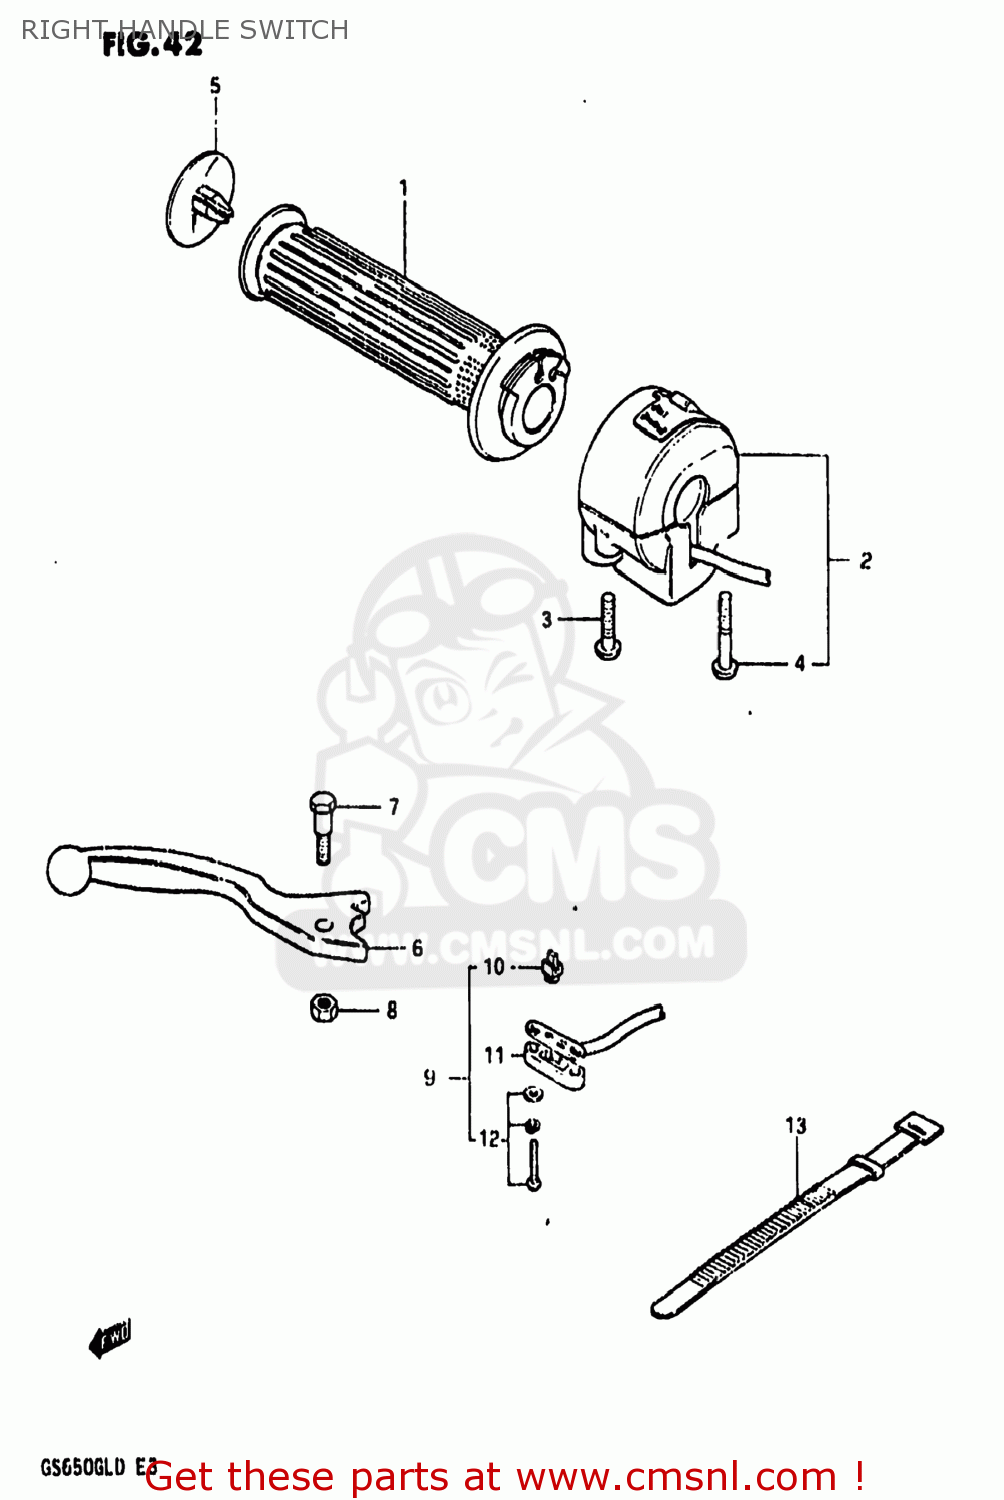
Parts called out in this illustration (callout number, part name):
1	GRIP,THROTTLE
2	SWITCH ASSEMBLY,HANDLE,RIGHT
3	SCREW
4	SCREW
5	CAP,GRIP END
6	LEVER,BRAKE
7	BOLT
8	NUT 6MM
9	SWITCH ASSEMBLY
10	CONTACT,SWITCH
11	COVER,FR BK TERMINAL BASE
12	SCREW
13	CLAMP(L:120)
